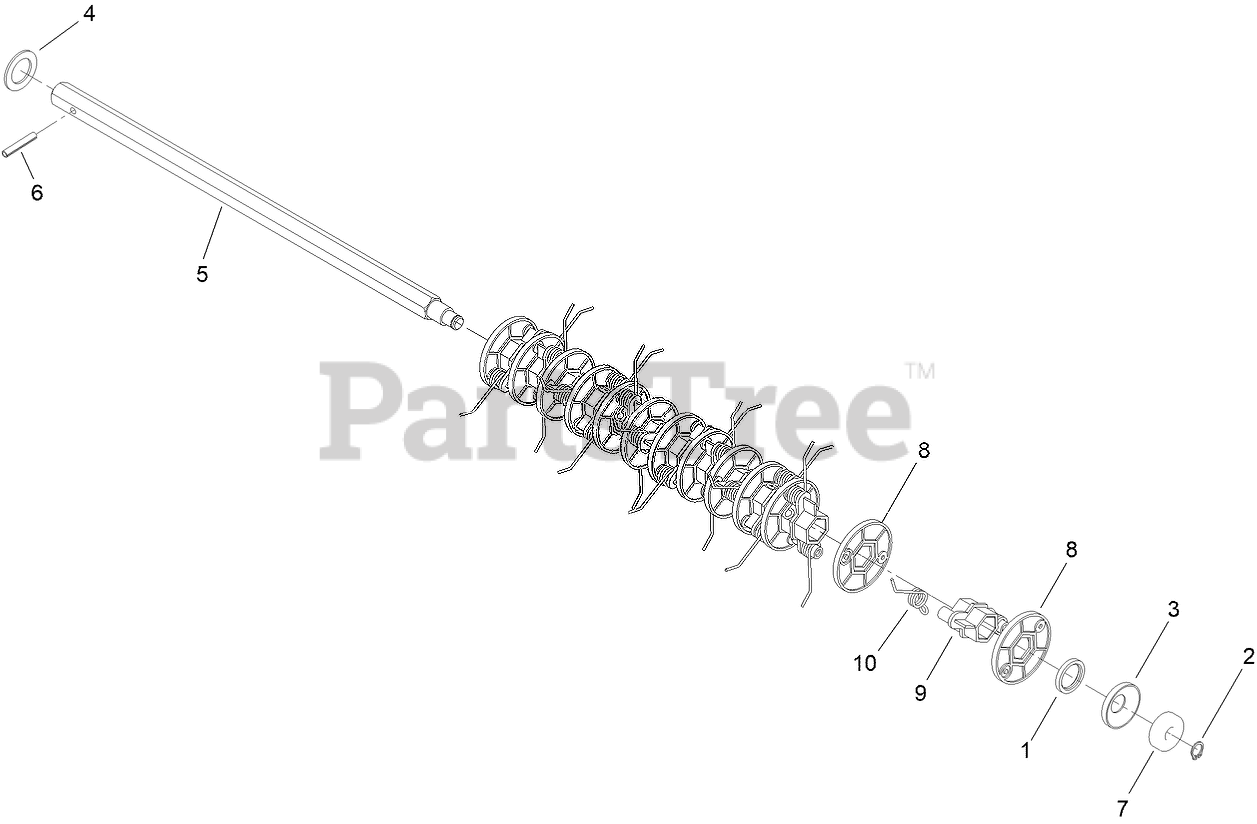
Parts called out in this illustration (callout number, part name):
1	SPACER
2	CIRCLIP
3	SHOULDER PIECE
4	WASHER
5	ROD-HEX
6	PIN-DOWEL
7	BEARING
8	DIVIDER-SPRING, PLASTIC AERATOR
9	RETAINER-SPRING, PLASTIC AERATOR
10	SPRING-AERATOR
